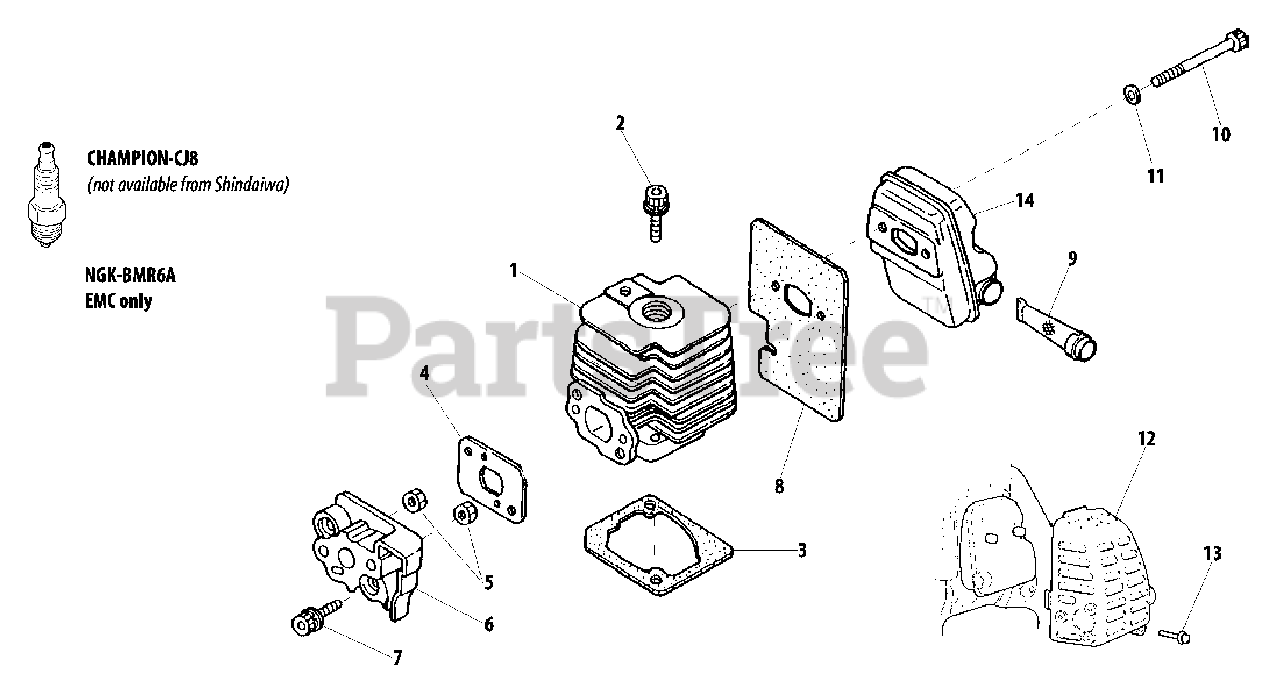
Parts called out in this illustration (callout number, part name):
1	CYLINDER
2	BOLT M5×25
3	GASKET, CYLINDER
4	GASKET
5	NUT M5×6.3
6	INSULATOR, INTAKE
7	BOLT M5×25
8	HEAT SHIELD, EXHAUST
9	SCREEN, SPARK ARRESTER
10	BOLT 5×40
11	WASHER, FLAT 5.5×10×0.8
12	COVER, MUFFLER
13	SCREW M5
14	MUFFLER
